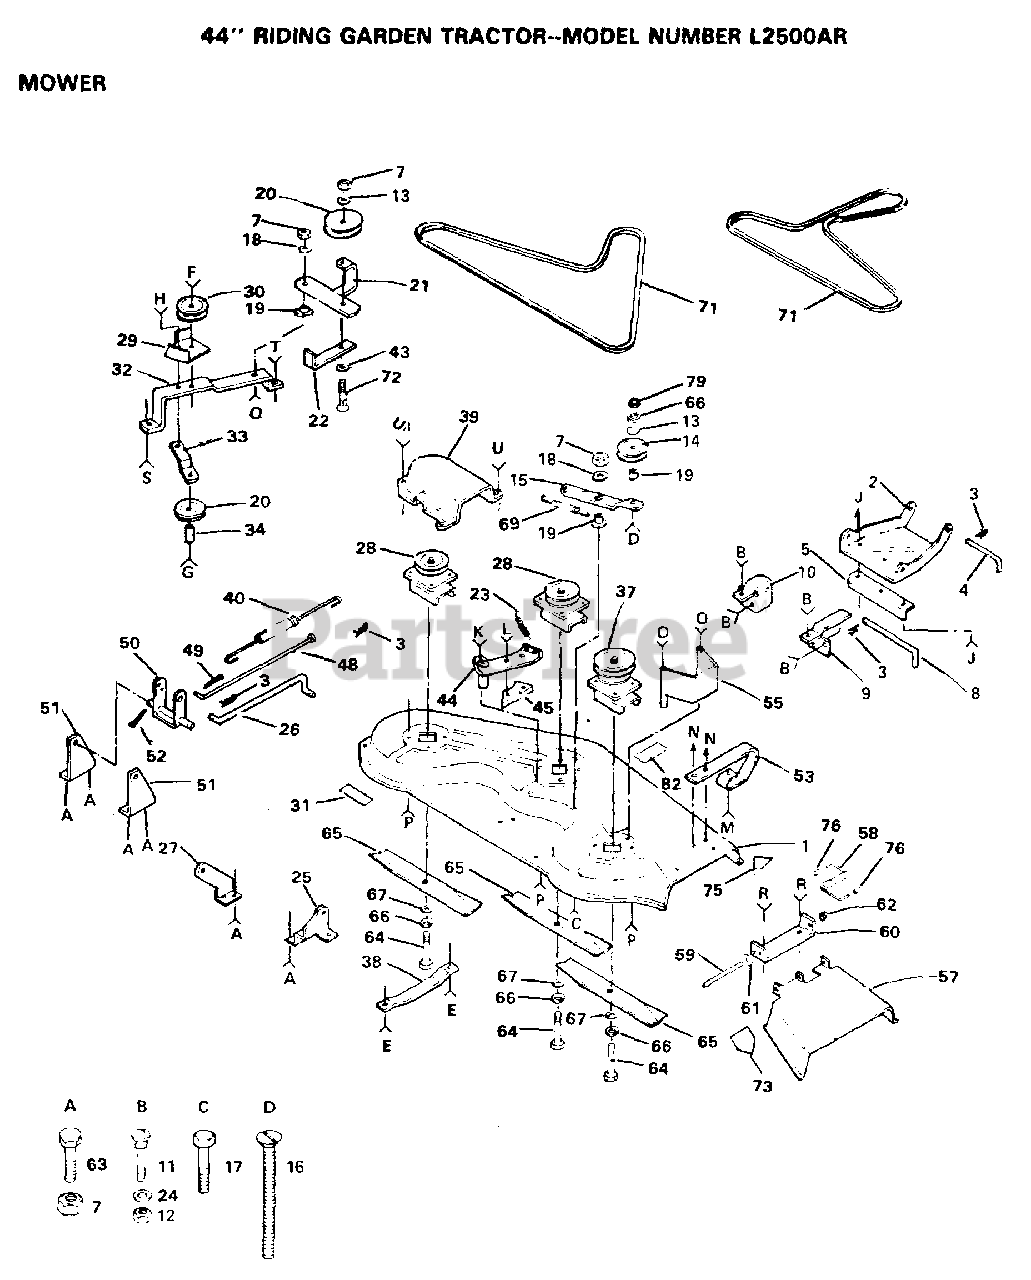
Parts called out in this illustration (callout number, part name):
1	Housing -Mower
2	LINK.PARALLEL
3	SPRING.RETAINER
4	"ROD, FRT. PARAL T"
5	LINK STOP
9	BRACKET RH YT
10	BRACKET LH YT
11	BOLT
13	WASHER
14	IDLER.FLAT.GTV
15	ARM-IDLER YT
16	SCREW YT
18	"WASHER, WEAR LT"
19	SPACER RETAINER
20	IDLER-FLAT T
23	SPRING-EXT YT
24	WASHER M
29	GUIDE-BELT YT
30	IDLER-INSIDE T
32	"SUPPORT YT, BAR"
33	BRACE-IDLER YT
38	RUNNER-LH M
39	GUARD YT
43	WASHER
44	BRAKE ARM LT
45	BRAKE-BLOCK YTV
48	ROD BRAKE YT
51	SUPPORT SHAFT YT
55	ASSY RH BELT GRD
57	DEFLECTOR SHIELD
59	ROD-HINGE T
61	WASHER
63	BOLT
64	BOLT.3/8-24X1-1/2
66	LOCKWASHER
67	WASHER
71	BELT-V.79.1.MWR
72	BOLT
75	DECAL - SAFETY STANDARD
76	CAP-SLEEVE LT
79	NUT.HEX.3/8-16UNC
82	DECAL.WARNING.T
